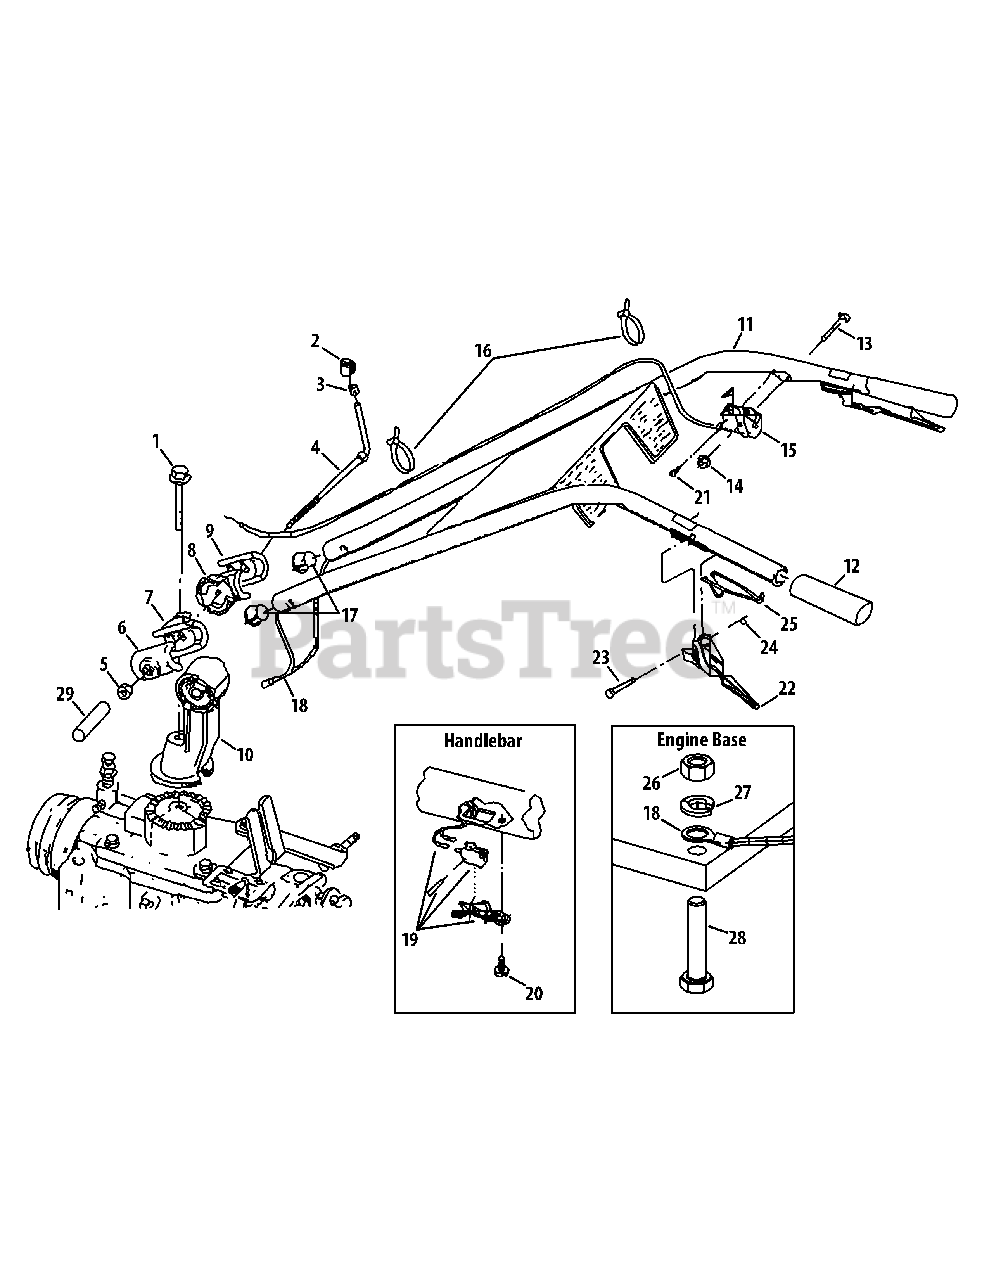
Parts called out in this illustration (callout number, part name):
1	Hex Bolt, 1/2-13 x 3-1/2
2	Handlebar Height Adjustment Knob
3	Retaining Ring
4	Handlebar Height Adjustment Stud
5	Hex Nut, 1/2-13
6	Handlebar Hgt, Adj. Clamp (LT)
7	Handlebar Hgt. Adj. Ratchet (LT)
8	Handlebar Hgt. Adj. Ratchet (RT)
9	Handlebar Hgt. Adj. Clamp (RT)
10	Handlebar Mounting Base
12	Handlebars Grip
13	Curved Head Bolt, 1.4-20 x 2
14	Hex Nut, 1.4h-20
15	Throttle Control & Cable, 66"
16	Plastic Tie
17	Wire Harness Retainer Plug
18	Handlebar Wire Harness Assembly
19	Switch Assembly
20	Pan Head Screw, #10-16 x 1/2
21	Phillips Head Screw, 10-32 x 1/2
22	Operator Presence Control Lever
23	Pivot Pin
24	Retaining Ring
25	Return Spring
26	Hex Nut, 5/16-18
27	Washer, 5/16
28	Hex Head Screw, 5/16-18 x 1.5
